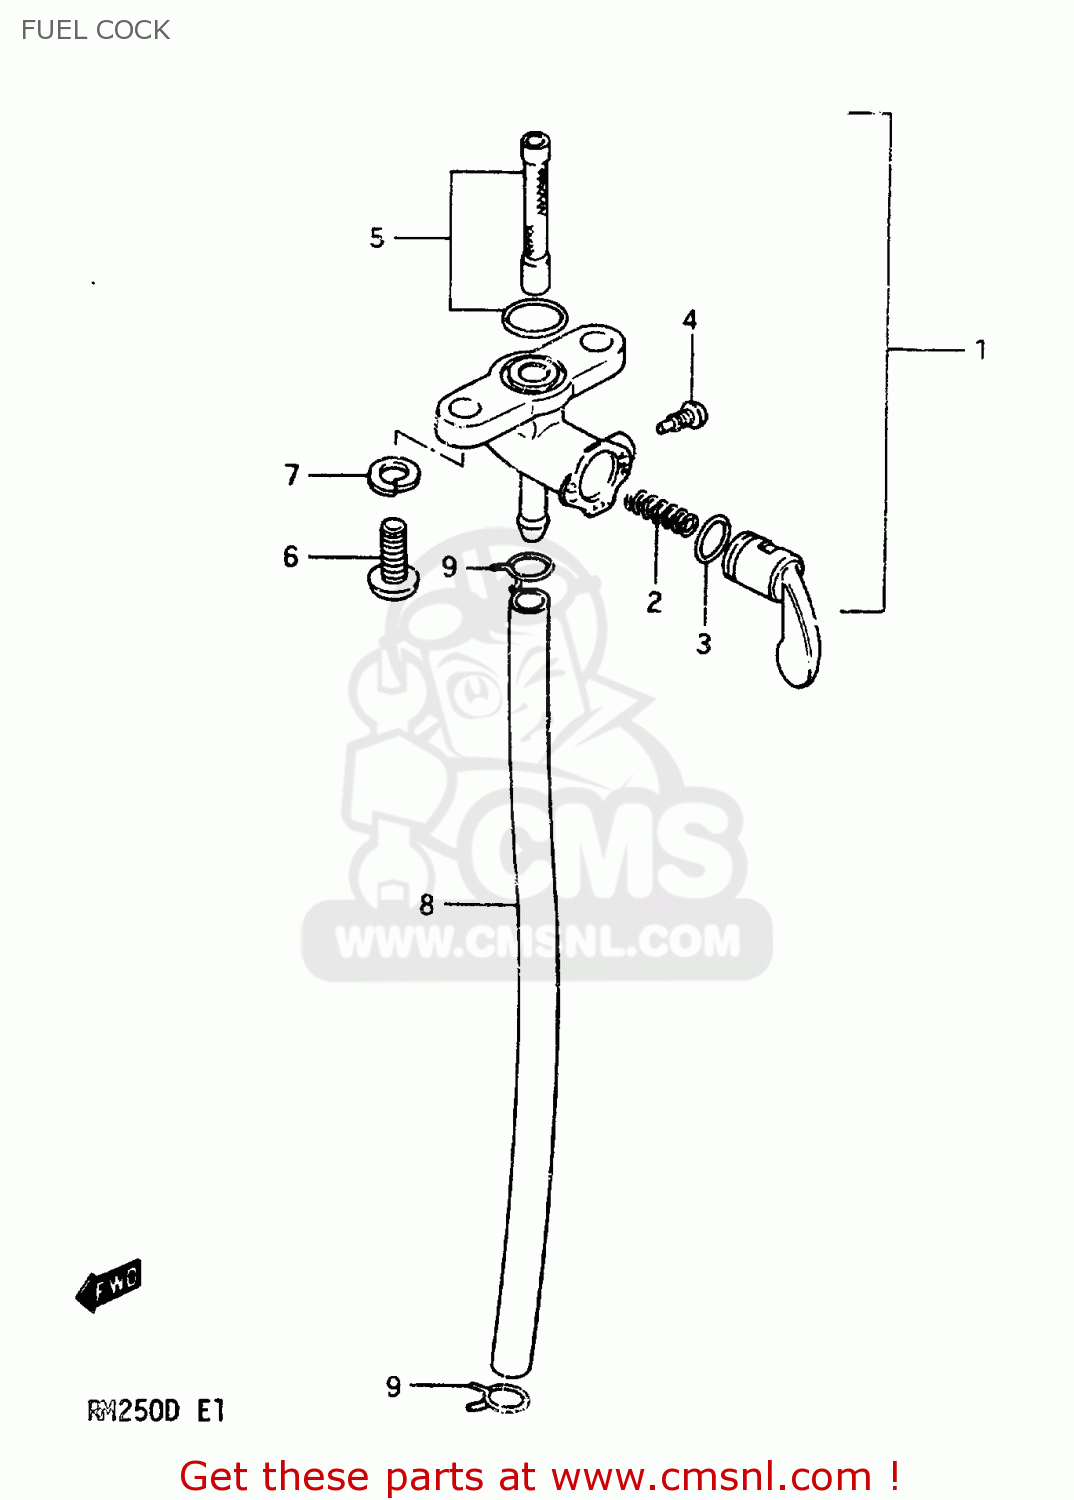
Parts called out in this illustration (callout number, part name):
1	COCK ASSY,FUEL
2	SPRING,FUEL COCK VALUE
3	O RING,LEVER
4	SCREW
5	FILTER SET FUEL
6	SCREW
7	WASHER,LOCK
8	HOSE
9	CLIP
